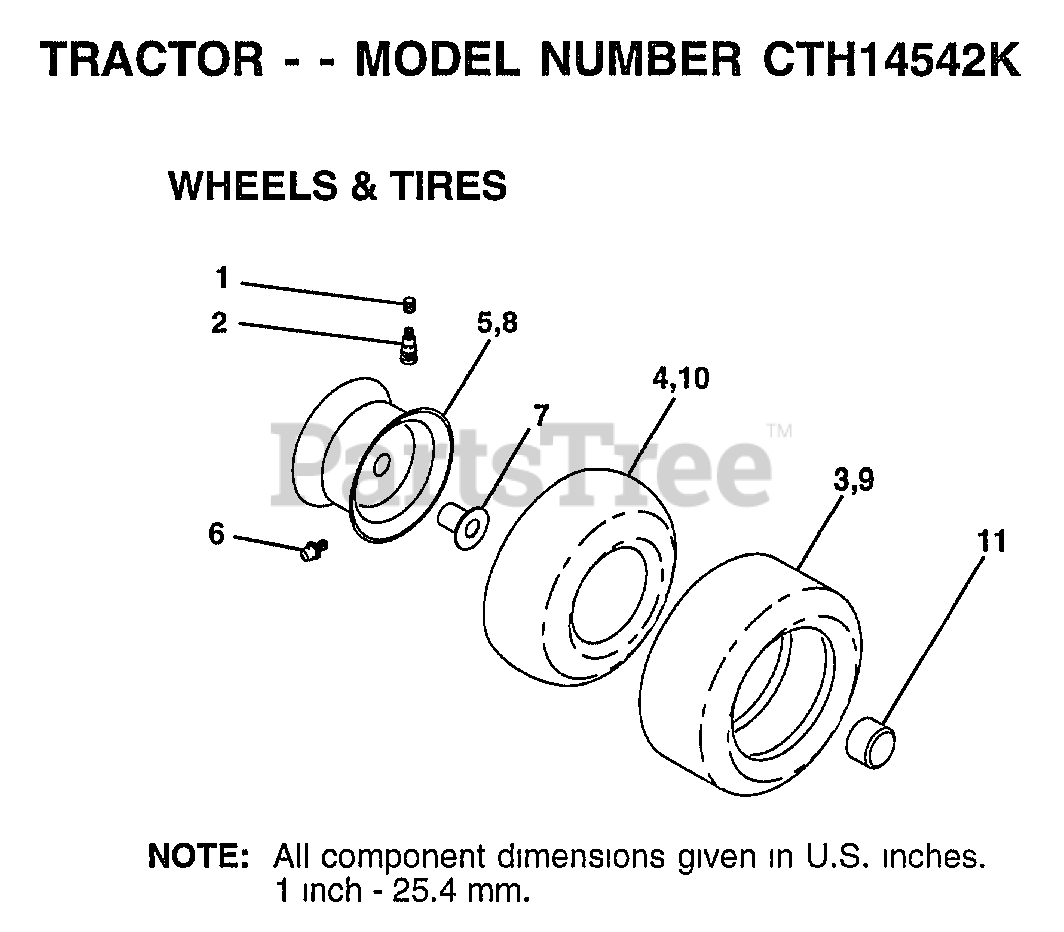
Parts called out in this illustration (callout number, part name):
1	VALVE CAP
2	VALVE STEM LT
4	TUBE.5.3/4.5/6
5	RIM.FRONT.6.YELLO
6	FITTING LT
7	"FLANGE, BEARING"
10	TUBE.18X9.5-8
11	HUB CAP
